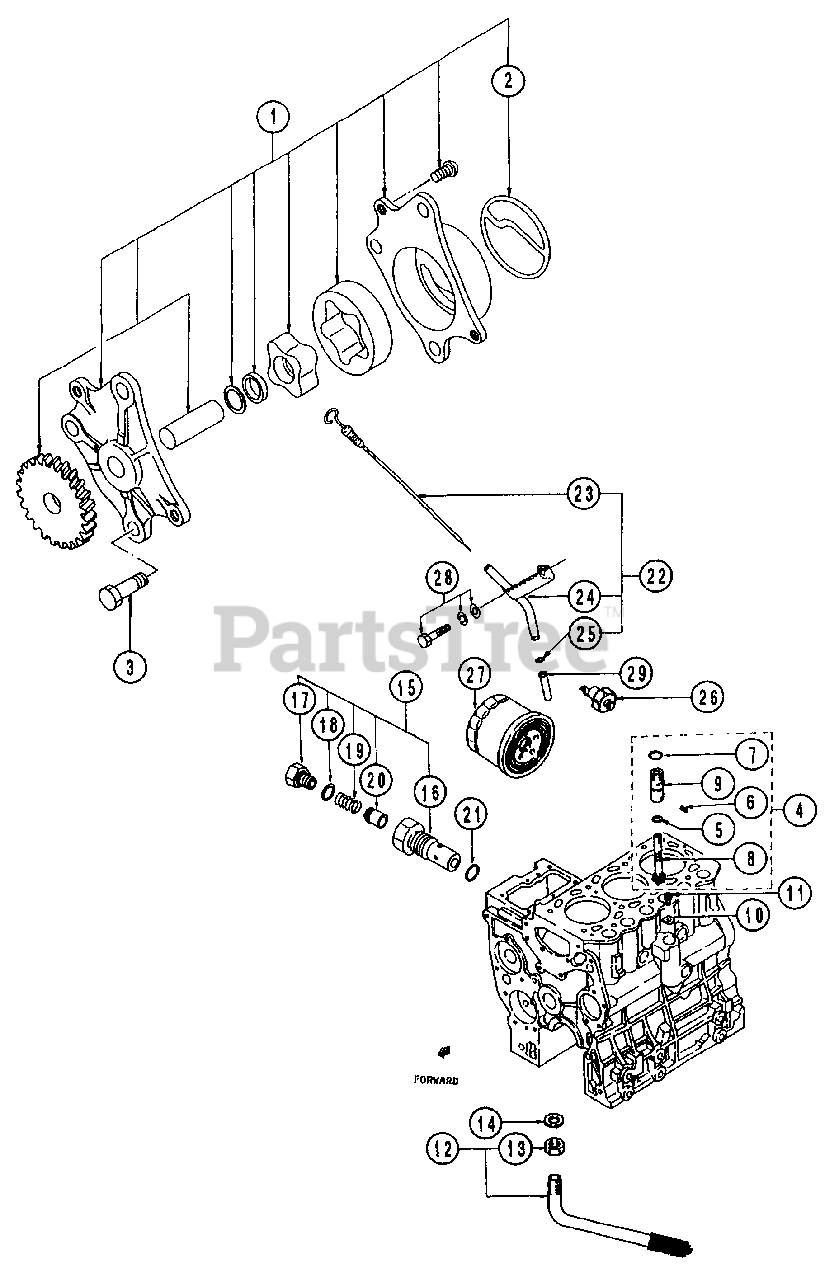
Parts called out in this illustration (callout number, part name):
1	Pump Ass'y, Oil
2	Packing, Body
4	Driven Unit
6	Pin, Spring
7	O-Ring
8	Gear
11	Bolt, W/Washer
12	Strainer Ass'y
15	Valve Ass'y, Relief
16	Housing, Valve
17	Plug
18	Gasket
19	Spring, Relief
20	Plunger, Relief
22	Gage & Guide Ass'y
23	Gauge Ass'y, Oil Level
24	Guide, Oil Level
25	O-Ring
27	Filter Ass'y
28	Bolt, W/Washer
29	Guide, Oil Level Gage
